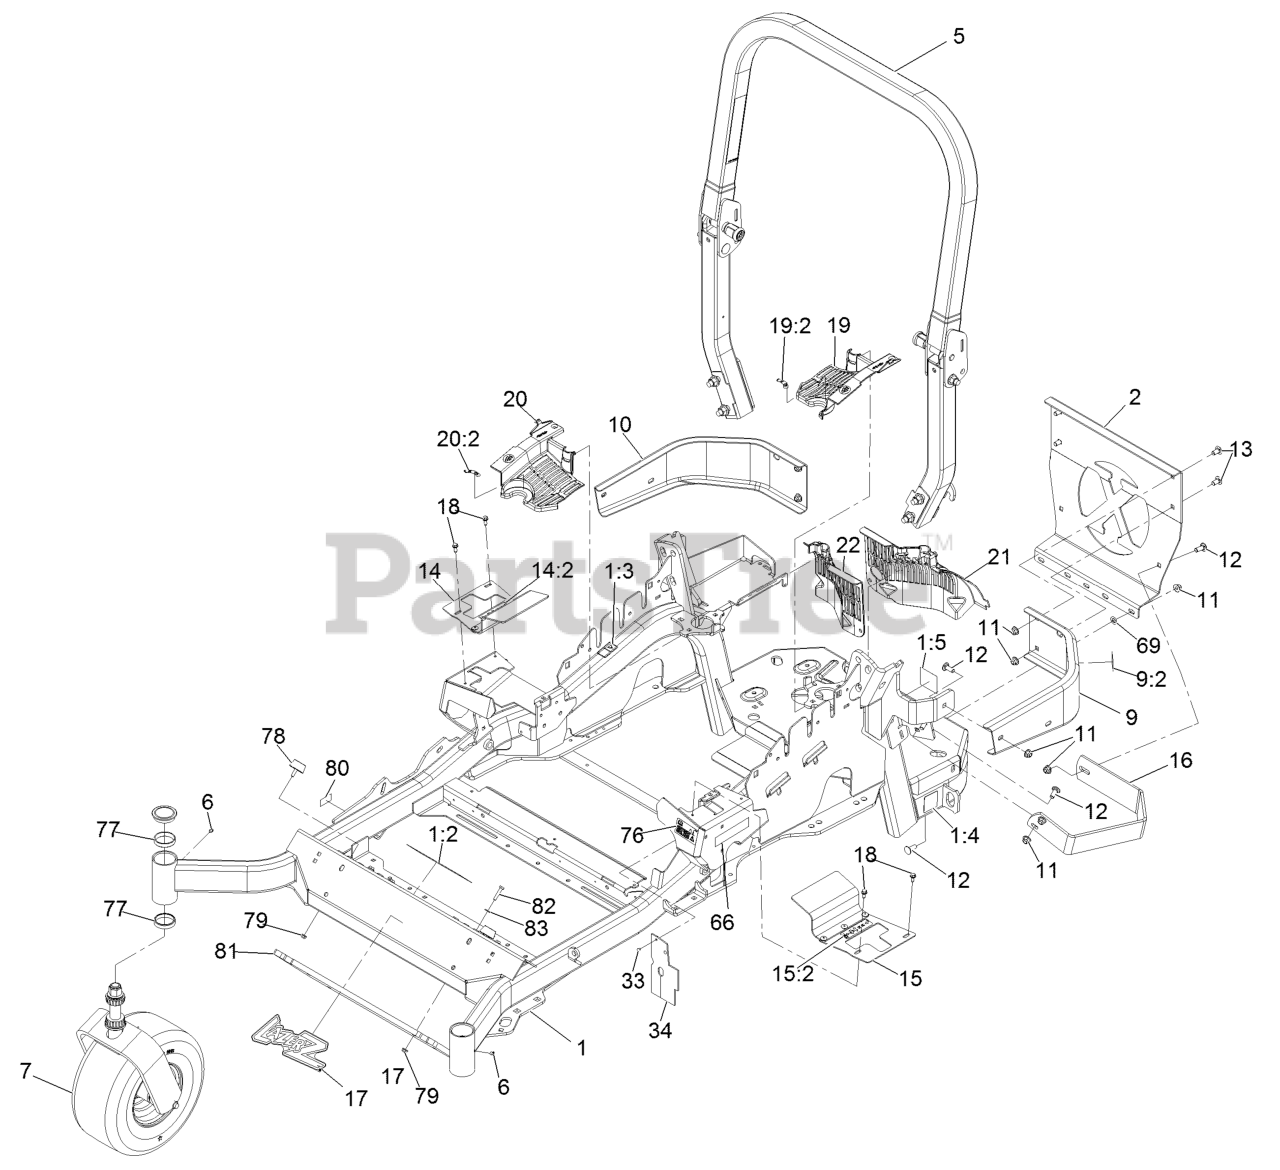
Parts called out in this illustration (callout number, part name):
1	MAINFRAME ASM
1:2	DECAL-WARNING, SLOPE
1:3	DECAL-WARNING
1:4	DECAL-HAZARD, PINCHED FINGER
1:5	DECAL-SPARK ARRESTER
2	PLATE,REAR GUARD
5	ASM,ROPS SERVICE EXMARK
7	Caster Wheel ASM
9	LH BUMPER ASM
9:2	DECAL-WARNING
10	BUMPER-RH
11	NUT-HF, NI
12	SCREW-CARR
13	SCREW-CARR
14	RH MOTION CONTROL COVER A
14:2	DECAL-CONTROL, MOTION
15	LH MOTION CONTROL COVER A
15:2	DECAL-CONTROL, MOTION
16	GUARD-MUFFLER
17	DECAL,LAZER MODEL
18	SCREW-HWH
19	LH HYDRO GUARD ASM
19:2	DECAL-OIL, HYDRO
20	RH HYDRO GUARD ASM
20:2	DECAL-OIL, HYDRO
21	GUARD-HYDRO, REAR (LH)
22	GUARD-HYDRO, REAR (RH)
33	RIVET-POP
34	DEFLECTOR-AIR FLOW
66	DECAL-X-SERIES
69	NUT-PUSH
76	DECAL-FUEL FILL, CE
77	CUP-BEARING
80	Decal-Patent Ttco.Com
81	WEIGHT-TOE BOARD
82	SCREW-HH
83	WASHER-FLAT
